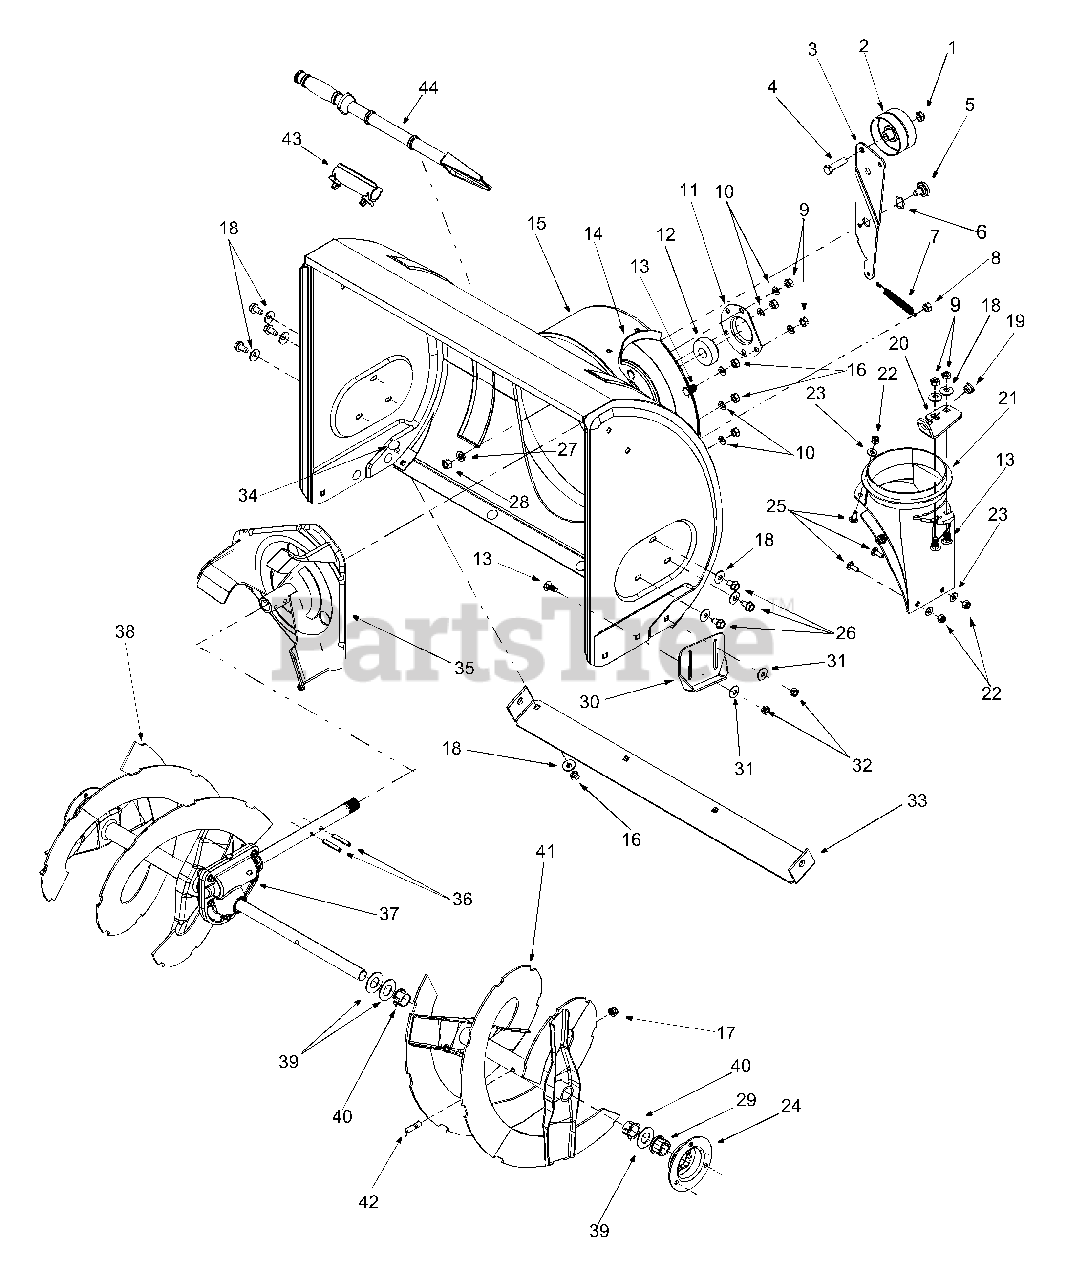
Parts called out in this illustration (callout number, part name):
1	Lock Jam Nut 3/8-24
2	Flat Idler, 2.75 w/o Flanges
4	H ex Cap Screw 3/8-24 x 50
5	Shoulder Screw
6	Flat Washer
7	Extension Spring
8	Hex Nut 5/16-18
9	Hex Nut 5/16-18
10	Lock Washer 5/16
11	Bearing Housing, 1.85
12	Ball Bearing, .75 x 1.85
13	Carriage Bolt 5/16-18 x .75
17	Lock Nut 5/16-18
18	Bell Washer
19	Plastic Bushing, .380
21	Chute Adapter, 5.0
22	Hex Lock Nut 1/4-20
23	Flat Washer
25	Carriage Screw 1/4-20 x .75
26	Hex Screw 5/16-18 x .75
27	Lock Washer 3/8
28	Hex Nut 3/8-16
29	Hex Flange Bearing
31	Bell Washer
32	Hex Nut 5/16-18
34	Carriage Bolt 5/16-18 x .62
36	Spiral Pin, .25 x 1.5
37	Gearbox Assembly (E663H)
40	Flange Bushing
42	Shear Bolt 5/16-18 x 1.5
43	Mount: Chute Clean-out Tool
44	Chute Clean-out Tool
